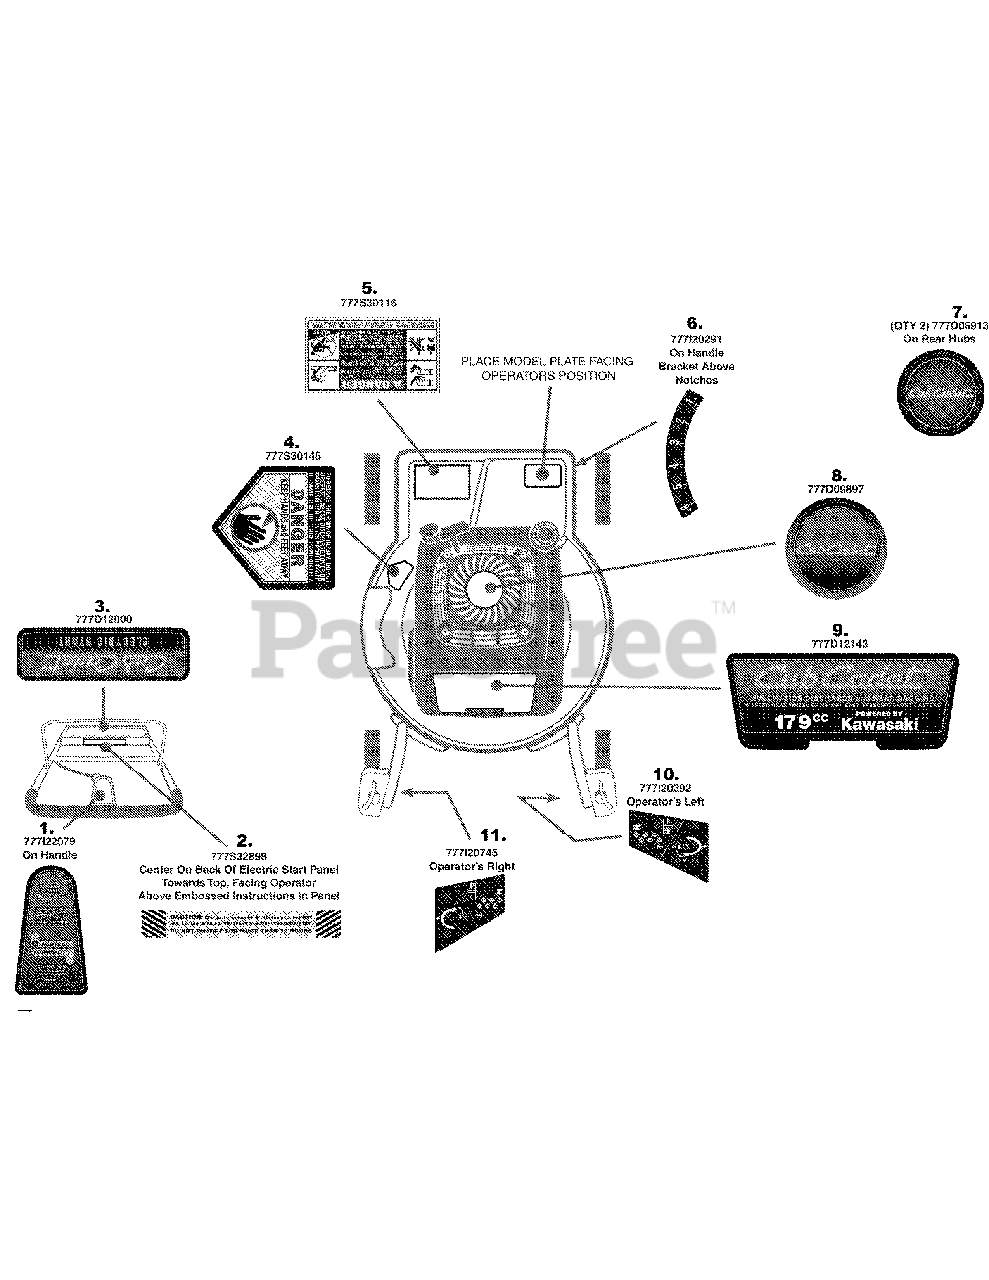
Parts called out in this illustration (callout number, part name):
1	LABEL-6 SPEED TRANS
2	LABEL-MOWER CHARGE CAUTION
3	LABEL-ELEC START CUB CADET
4	LABEL
5	LABEL-MOWER DANGER
6	LABEL-HEIGHT ADJUS
7	LABEL-HUB CAP
8	LABEL-ENGINE SPINNER CUB CADET
9	LABEL-179CC SHROUD KAW
10	LABEL-CASTOR LOCK
11	LABEL-CASTOR LOCK
